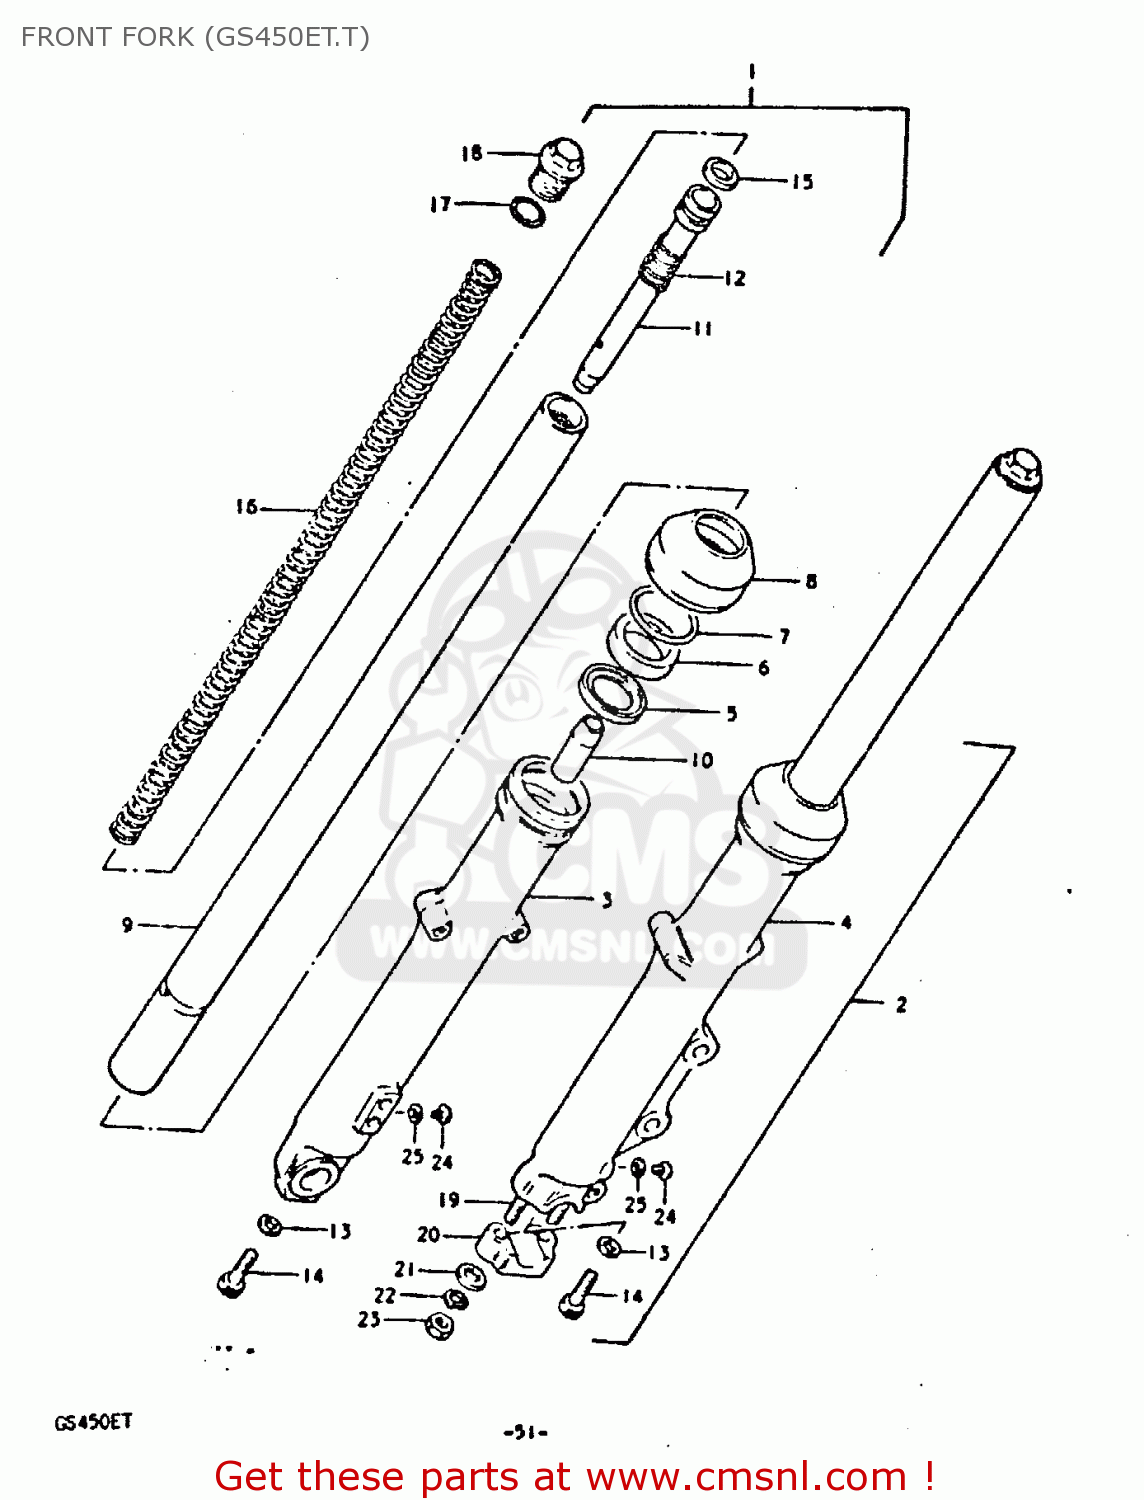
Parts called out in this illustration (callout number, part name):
1	DAMPER ASSEMBLY,RIGHT
2	DAMPER ASSEMBLY,LEFT
3	TUBE,FORK,OUTER,RIGHT
4	TUBE,FORK,LEFT,OUTER
5	SPACER,OIL SEAL
6	OIL SEAL,FRONT FORK
7	CIRCLIP,FORK OIL SEAL
8	BOOT
9	TUBE,INNER
10	PIECE,OIL LOCK
11	CYLINDER,FRONT FORK
12	SPRING,REBOUND
13	GASKET (NAS)
14	BOLT(8X27)
15	RING,PISTON
16	SPRING
17	O RING
18	BOLT
19	STUD 8X25
20	HOLDER,AXLE
21	WASHER
22	LOCK WASHER
23	NUT (8MM)
24	SCREW 4X6
25	GASKET (NAS)
